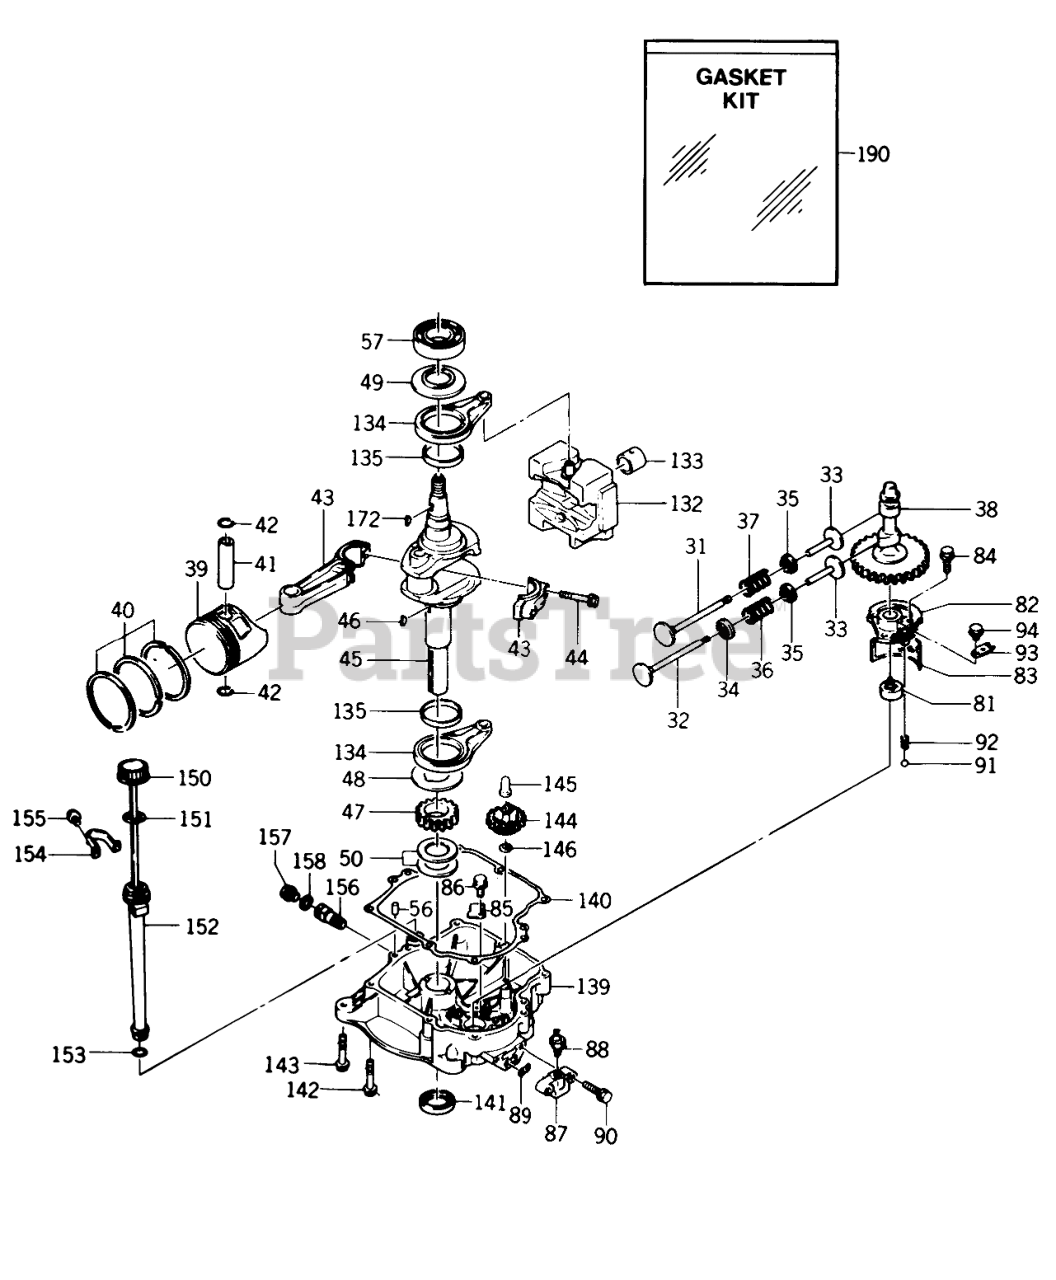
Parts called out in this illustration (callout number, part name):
31	VALVE-INTAKE
32	VALVE-EXHAUST
33	TAPPET-VALVE
34	ROTATOR-VALVE
35	RETAINER-VALVE
36	SPRING-VALVE
37	SPRING-VALVE
38	Cam Shaft
39	PISTON-STD
39	PISTON-.010 O/S
39	Piston-.020 Over Size
39	Piston-.030 Over Size
40	RING PISTON-STD
40	Piston Ring Set-.010 Over Size
40	RING-PISTON-.020
40	RING PISTON-.030
41	PIN-PISTON
42	RING-SNAP
43	Connecting Rod Ass-y-Standard (includes item 44)
43	Connecting Rod Ass-y-.025mm Under Size (Includes item 44)
44	BOLT-CON ROD
45	Crankshaft Complete
46	KEY-WOODRUFF
47	Helical Gear
48	SPACER
49	SPACER
50	SHIM-T=1.18
50	SHIM-T=1.25
50	SHIM-T=1.32
50	SHIM-T=1.39
50	SHIM-T=1.46
50	SHIM-T=1.53
50	SHIM-T=1.60
50	SHIM-T=1.67
50	SHIM-T=1.74
57	BEARING-BALL #6207
81	PUMP OIL
82	COVER-PUMP
83	FILTER-INTERNAL OIL
84	BOLT, FLANGED 8X25
85	PLATE
86	Bolt
87	COVER
88	SWITCH-OIL PRESSURE
89	RING O
90	BOLT-FLANGED (8X30)
91	BALL-STEEL 5/16
92	SPRING
93	PLATE
94	BOLT-FLANGED
132	Weight Complete (includes item 133)
133	BEARING-PLAIN
134	Rod Assy (includes item 135)
135	BEARING PLAIN
139	COVER-CRANKCASE
140	GASKET
141	SEAL OIL
142	BOLT-FLANGED
143	BOLT, FLANGED 8X25
144	GOVERNON
145	SLEEVE-GOVERNOR
146	WASHER
150	GAUGE-OIL
151	GASKET
152	FILLER
153	O-RING
154	CLAMP
155	Bolt
156	JOINT
157	PLUG DRAIN
158	GASKET
172	KEY-WOODRUFF
190	GASKET SET-OVERHAUL
